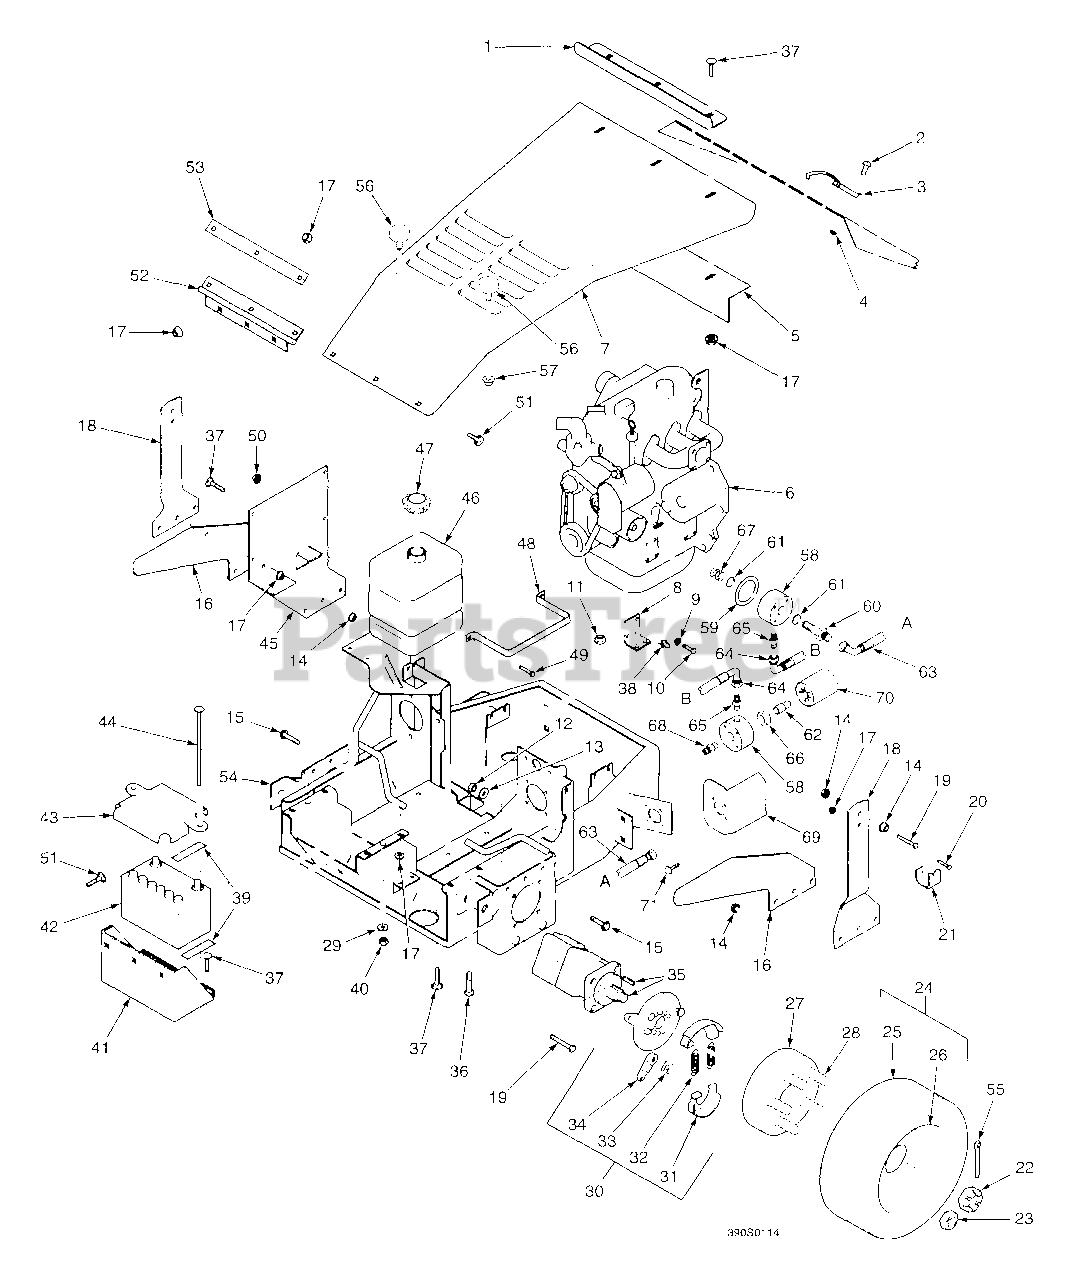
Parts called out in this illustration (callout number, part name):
1	Catch, Hood Latch
2	Screw, Round Head Washer, #10-32 x 1/2
3	Latch, Hood
4	Hex Nut, #10-32
5	Stiffener, Hood
6	Engine, Kubota, 28 HP Diesel
8	Mounting Plate, Engine
9	Lockwasher, 7/16
10	Bolt, Hex Head, M10-1.25 x 25
11	Hex Locknut, Elastic Stop, 7/16-14
12	Hex Nut, 1/2-13
13	Lockwasher, 1/2
14	Serr. Fl. Hex Nut, 1/2-13
15	Serr. Fl. Hex Head Capscrew, 1/2-13 x 1-1/2
16	Stop, Cutter Deck
17	Serr. Fl. Hex Nut, 5/16-18
18	Anchor, Deck Spring
19	Bolt, Hex Head, 1/2-13 x 2-1/2
20	Serr Fl. Hex Head Capscrew, 5/16-18 x 3/4
21	Retainer, Spring
22	Castle Nut, 1.0-20 UNEF
23	Nut, Wheel
24	Wheel Assembly
25	Tire, 23 x 1050 -12, 4-ply
27	Hub, Wheel
28	Bolt, Hub
29	Flat Washer, 5/16 (.375 x .875 x .083)
30	Parking Brake Assembly
31	Brake Pads - Pair
32	Springs - Pair
34	Actuating Arm
35	Motor, Hydraulic - White
36	Bolt, Hex Head, 7/16-14 x 1-1/4
37	Carriage Bolt, 5/16-18 x 3/4
38	Stud, Metric
39	Pad, Rubber
40	Hex Locknut, Elastic Stop, 5/16-18
41	Battery Box
42	Battery
43	Hold Down, Battery
44	Carriage Bolt, 5/16-18 x 10
45	Support Bracket, Hydraulic Tank
46	Hydraulic Tank
47	Cap, Hydraulic Tank
48	Strap, Hydraulic Tank
49	Serr Fl. Hex Head Capscrew, 1/4-20 x 3/4
50	Hex Locknut, Elastic Stop, 1/4-20
51	Carriage Bolt, 5/16-18-1/2
52	Hinge
53	Plate, Hinge
54	Engine Deck
55	Pin, Cotter, 5/32 x 1-1/2
56	Bumper, Rubber
57	Nut, 5/16-18 Serrated Flange
58	Adapter, Remote Oil Filter
59	Gasket, Oil Filter Adapter
60	MTG Bolt, Filter Adapter
61	O-Ring
62	Reducer, Remote Filter
63	Hose Assy, Remote Filter
64	Hose Assy, Remote Filter
65	Connector, 1/2 Pipe x 3/4 JIC
66	Nut, 7/8-14
67	Spring Filter Adapter
68	Tube Union, 7/8-14 JIC x O-Ring
69	Guard Oil Filter
70	Oil Filter, Engine
71	Bolt, 1/4-20 X 75 Hex Head
